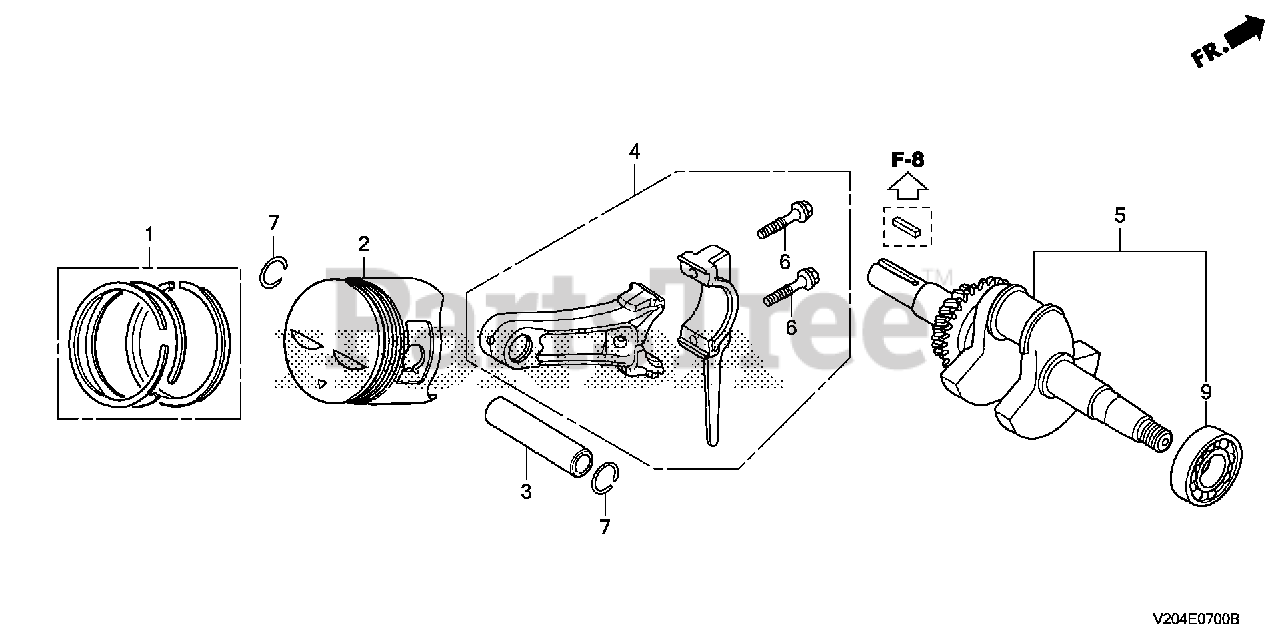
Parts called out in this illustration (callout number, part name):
1	RING SET, PISTON (STD) (TEIKOKU)
1	RING SET, PISTON (0.25) (TEIKOKU)
1	RING SET, PISTON (0.50) (TEIKOKU)
1	RING SET, PISTON (0.75) (TEIKOKU)
2	PISTON (STD)
2	PISTON (0.25)
2	PISTON (0.50)
2	PISTON (0.75)
3	PIN, PISTON
4	ROD ASSY., CONNECTING (Honda Code 2110153). (US 0.25)
4	ROD ASSY., CONNECTING (STD)
5	CRANKSHAFT
6	BOLT, CONNECTING ROD
7	CLIP, PISTON PIN (18MM)
9	BEARING, RADIAL BALL (6206)
